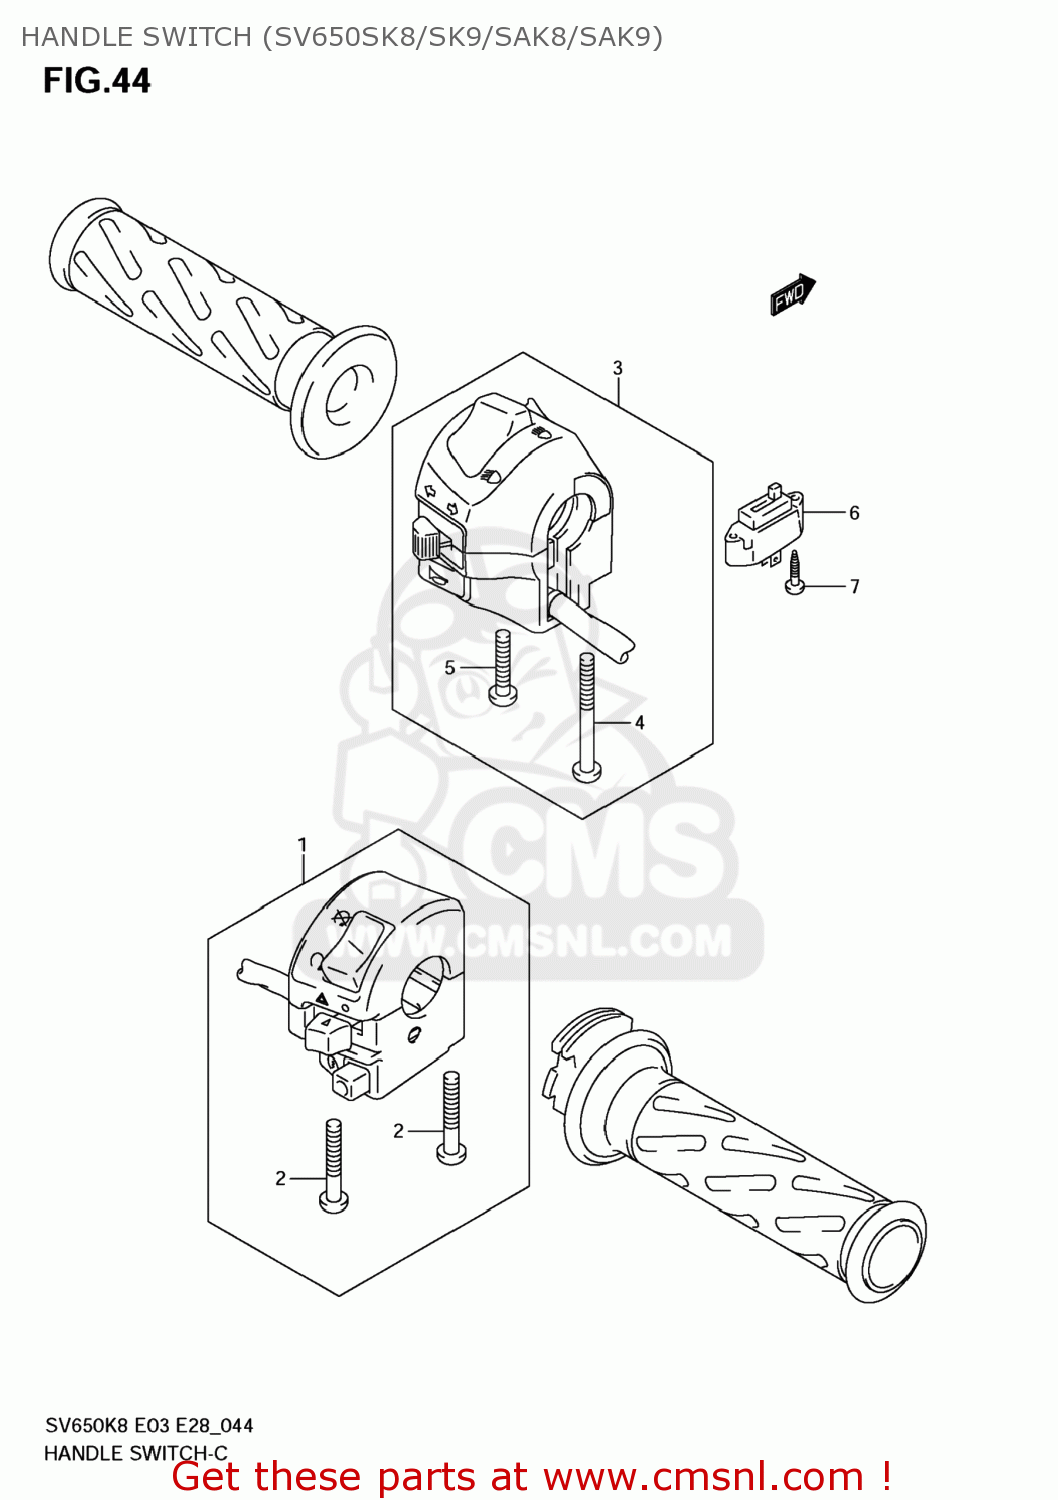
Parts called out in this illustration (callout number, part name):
1	SWITCH ASSY,HANDLE,R
2	SCREW, 5X45
3	SWITCH ASSY,HANDLE,L
4	SCREW, 5X45
5	SCREW(5X25)
6	SWITCH ASSY,CLUTCH
7	SCREW(3X14)
